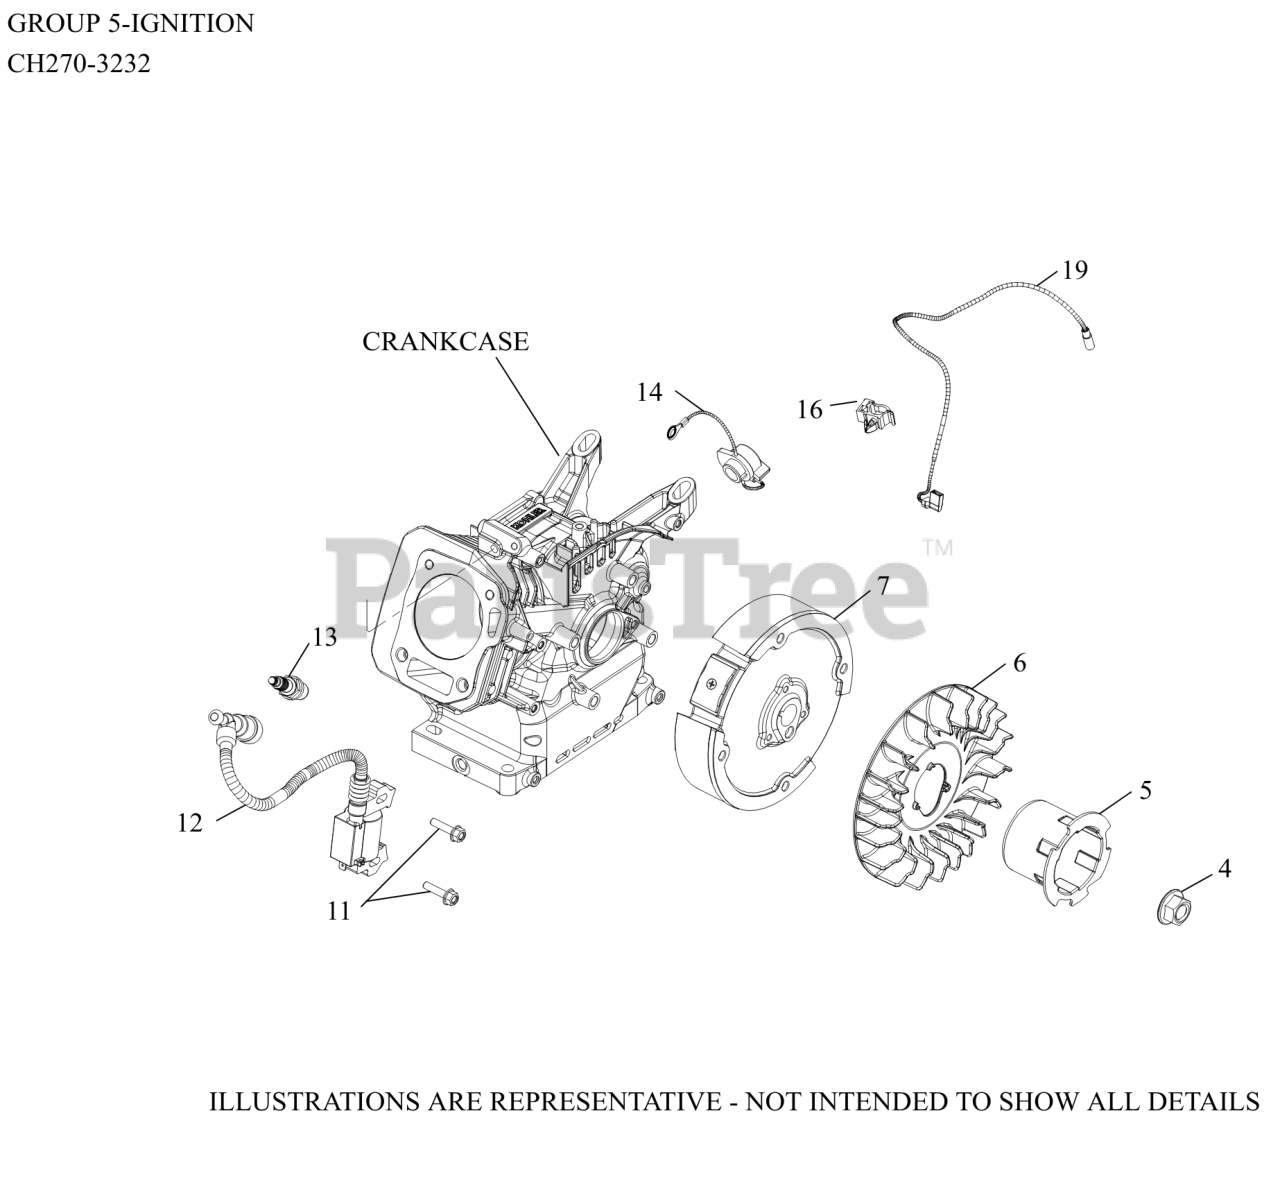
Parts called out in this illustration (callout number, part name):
4	NUT, FLYWHEEL
5	CUP, STARTER DRIVE
6	FAN, FLYWHEEL
7	FLYWHEEL ASSY,CAST IRON-(#1702528S)
11	SCREW, M6 X 25-(#25086436S)
12	MODULE, IGNITION
13	SPARK PLUG
14	SWITCH, IGNITION
16	CLIP, WIRE HARNESS
19	LEAD, GROUND TO KILL
